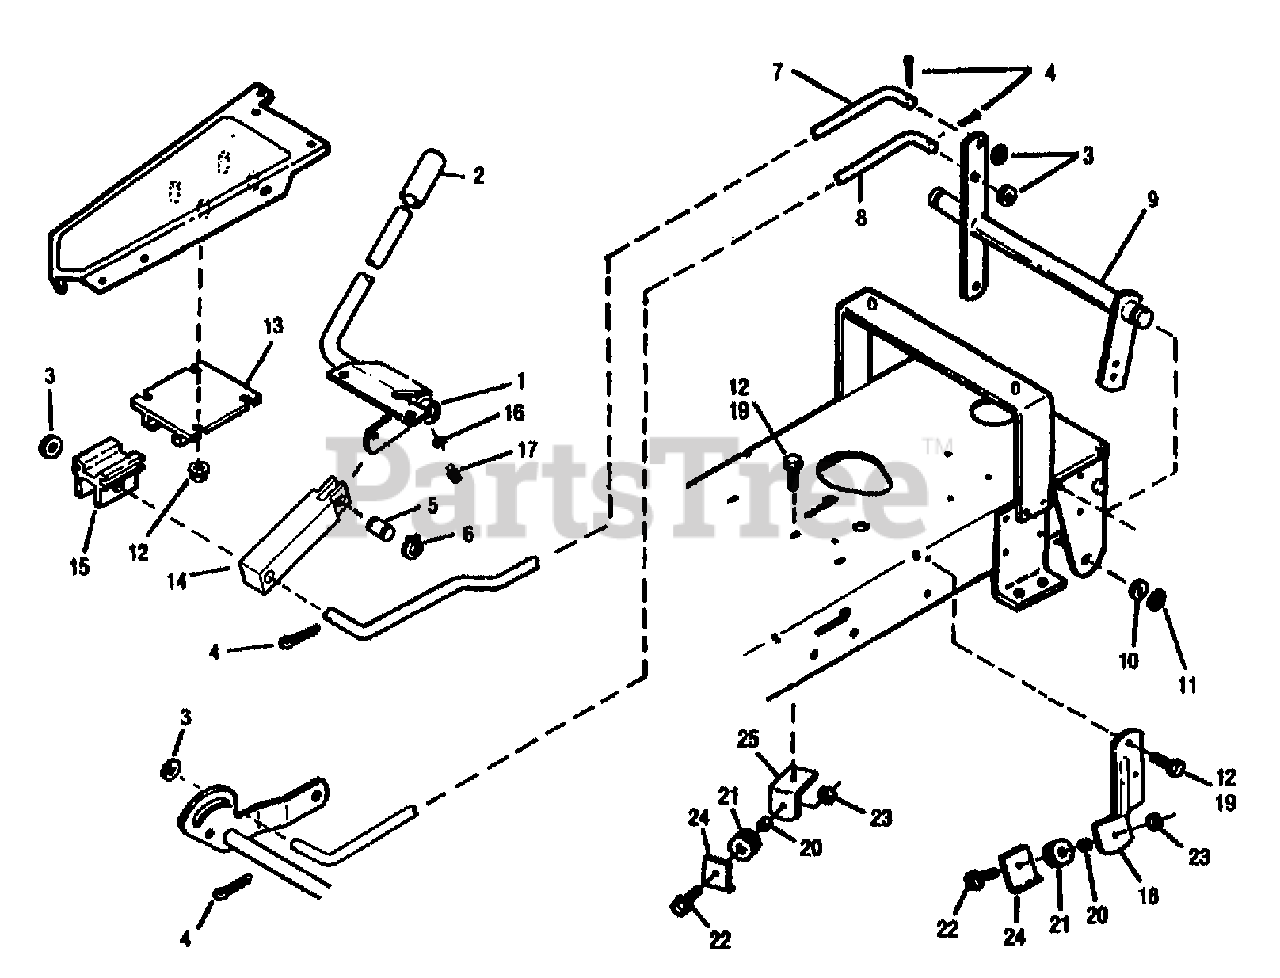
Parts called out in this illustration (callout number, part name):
1	LIFT LEVER ASSY
2	GRIP-FLEX
3	WASHER-1.06X.531X.1 ZP
4	PIN-COTTER .120X1.00 ZP
6	RING-RETAINING
7	ROD-LIFT
9	ASSM-LIFT SHAFT
10	WASHER-1.38 X.765X .06 ZP
11	RING-RET."E".577 ID
12	NUT-HFLK 5/16-18 ZP
13	KIT-GUIDE (TRACTOR)
14	LINK-PUSH
15	KIT-GUIDE (TRACTOR)
16	BEARING-FLANGE
17	FITTING-GREASE
19	SCR-LOCK
20	SPACER-.75X.40X.51 P/M
21	PULLEY-CABLE
22	SCR-HH 3/8-16X1.25
23	NUT-LOCK 3/8-16
24	GUIDE-CABLE
